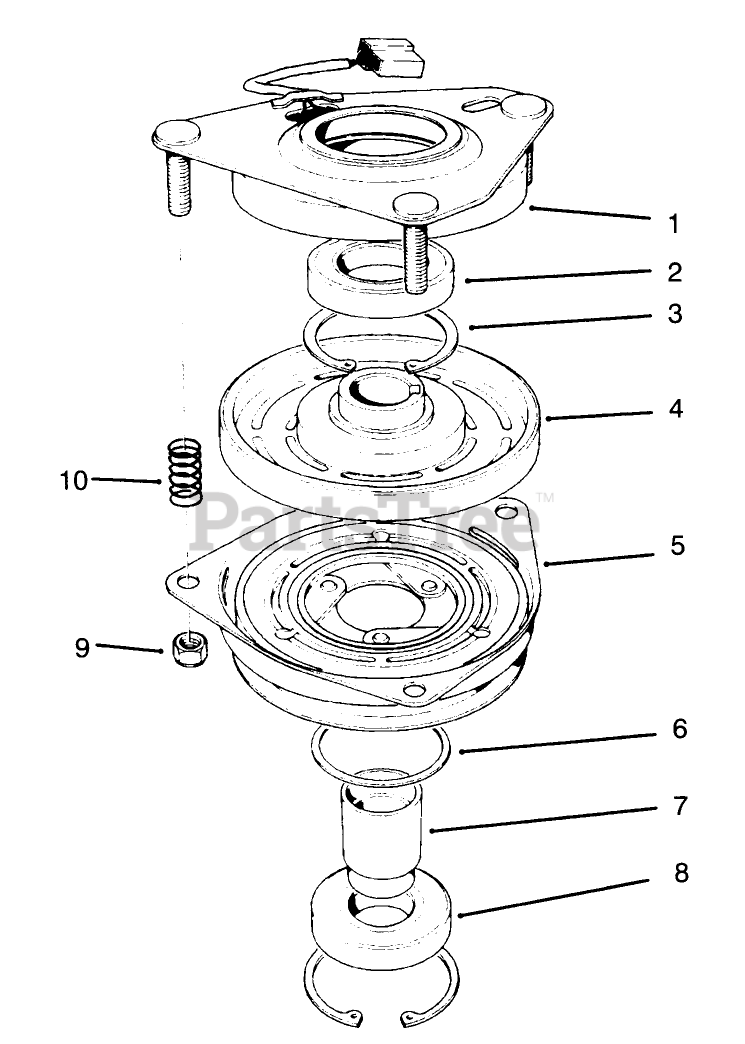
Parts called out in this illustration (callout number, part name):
1	Field Assembly (Incl. Ref. #2 & 3)
2	BEARING-FIELD
3	RING-RETAINING
4	Field Coil, Rotor & Bearing Assembly (Incl. Ref. #1)
5	Armature & Pulley Assembly (Incl. Ref. #3, 6, 7, & 8)
6	SPACER-BEARING, PULLEY
7	COLLAR-BEARING
8	BEARING-PULLEY
9	NUT-HEX
10	SPRING
